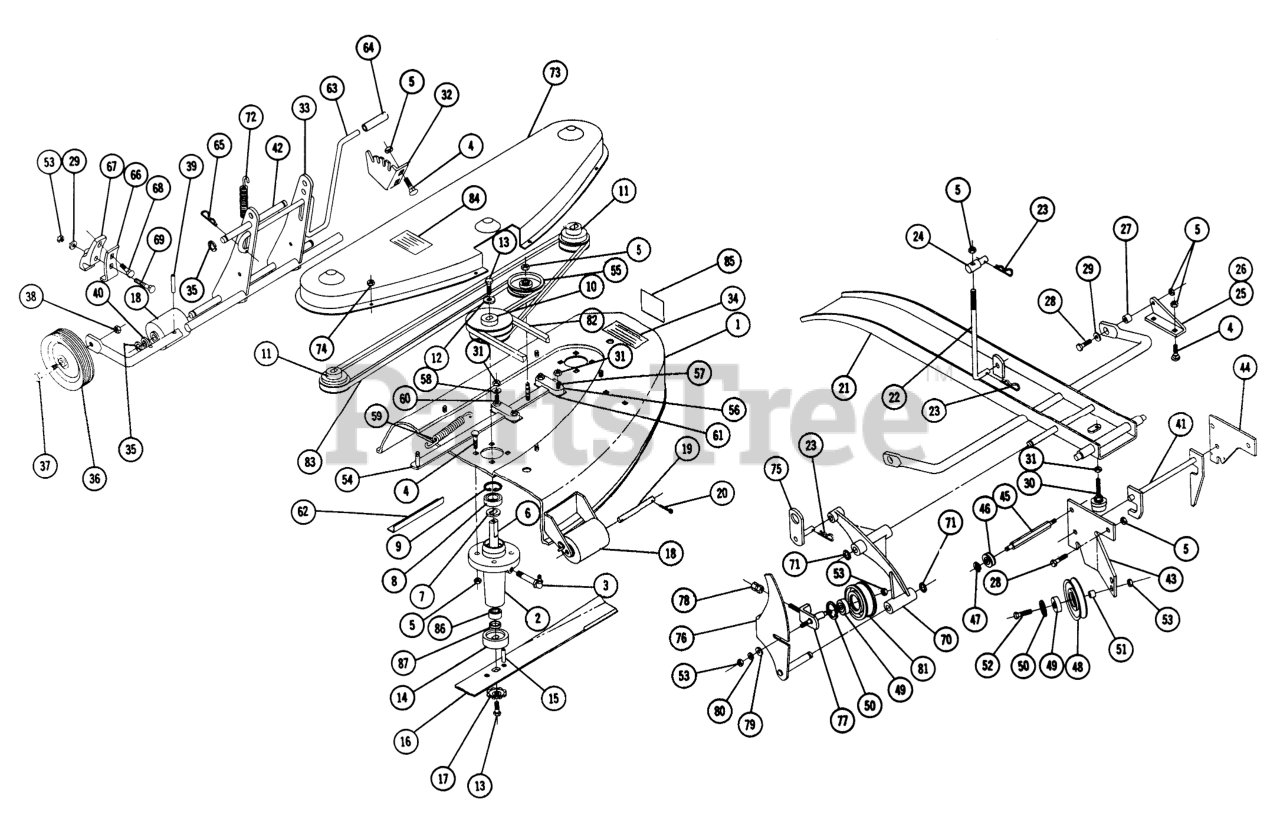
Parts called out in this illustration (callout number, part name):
1	Ass-y. Deck 42" Mower
2	Housing
3	Fitting-Grease
4	Bolt 3/8-16 x 1
5	3/8-16 E.S.
6	Shaft Spindle
7	WASHER
8	Ball
9	INT SNAP RING
10	Center Pulley
11	End Pulley
12	WASHER
13	Bolt 3/8-16 x 7/8
14	SPINDLE CUP
15	SPIROL ROLL PIN
16	Blade 14"
17	WASHER
18	Roller
19	Shaft
20	Cotter Pin
21	Washer
22	ROD LIFT
23	Hairpin
24	TRUNNION-LIFT
25	Bracket Deck R.H.
26	Bracket Deck L.H.
27	SPACER
28	Bolt 3/8-16 x 1
29	Washer
30	Leveler
31	Nut 5/16-18
32	Quadrant
33	Ass-y. Gage Wheel Support
34	Decal
35	E Ring
36	Wheel
37	BOLT-SHOULDER
38	Nut-Jam 3/8-16
39	Roll Pin
40	Washer
41	ASSY LATCH & SHAF R
42	Pin
43	MOUNTING BRACKET R
44	PLATE-MTG BRKT LH R (NS)
45	SUPPORT MTG PLATE
46	ROLLER
47	Lock Rod
48	PULLEY IDLER
49	BEARING
50	INTERNAL SNAPRING
51	SPACER
52	Bolt, 3/8-16 x 1/2
54	ASSY BAR IDLER SUPPO
55	Idler Pulley
56	Side Block
57	Bolt-5/16-18 x 1/4
58	Washer
59	SPRING R
60	Bolt-5/16-18 x 1 1/2
61	SLIDE
62	ANGLE
63	Rod-Height Control
64	Grip Handle
65	Hairpin
66	Clip-Axle
67	SUPPORT AXLE
68	Bolt-Carriage
69	Bolt Carriage 3/8-16 x 1
70	ARM PIVOT R
71	RING LAM L 262
72	Spring
73	Cover
74	HEX NUT 10-32 E.S.
75	Cam Arm
76	Ass-y Cam Lever
77	Ass-y Idle Support
78	Nut
79	Washer
80	Lockwasher
81	PULLEY IDLER
82	Screw
83	V BELT
84	Decal Belt Installation
85	Decal
86	NEEDLE BEARING
87	Seal
